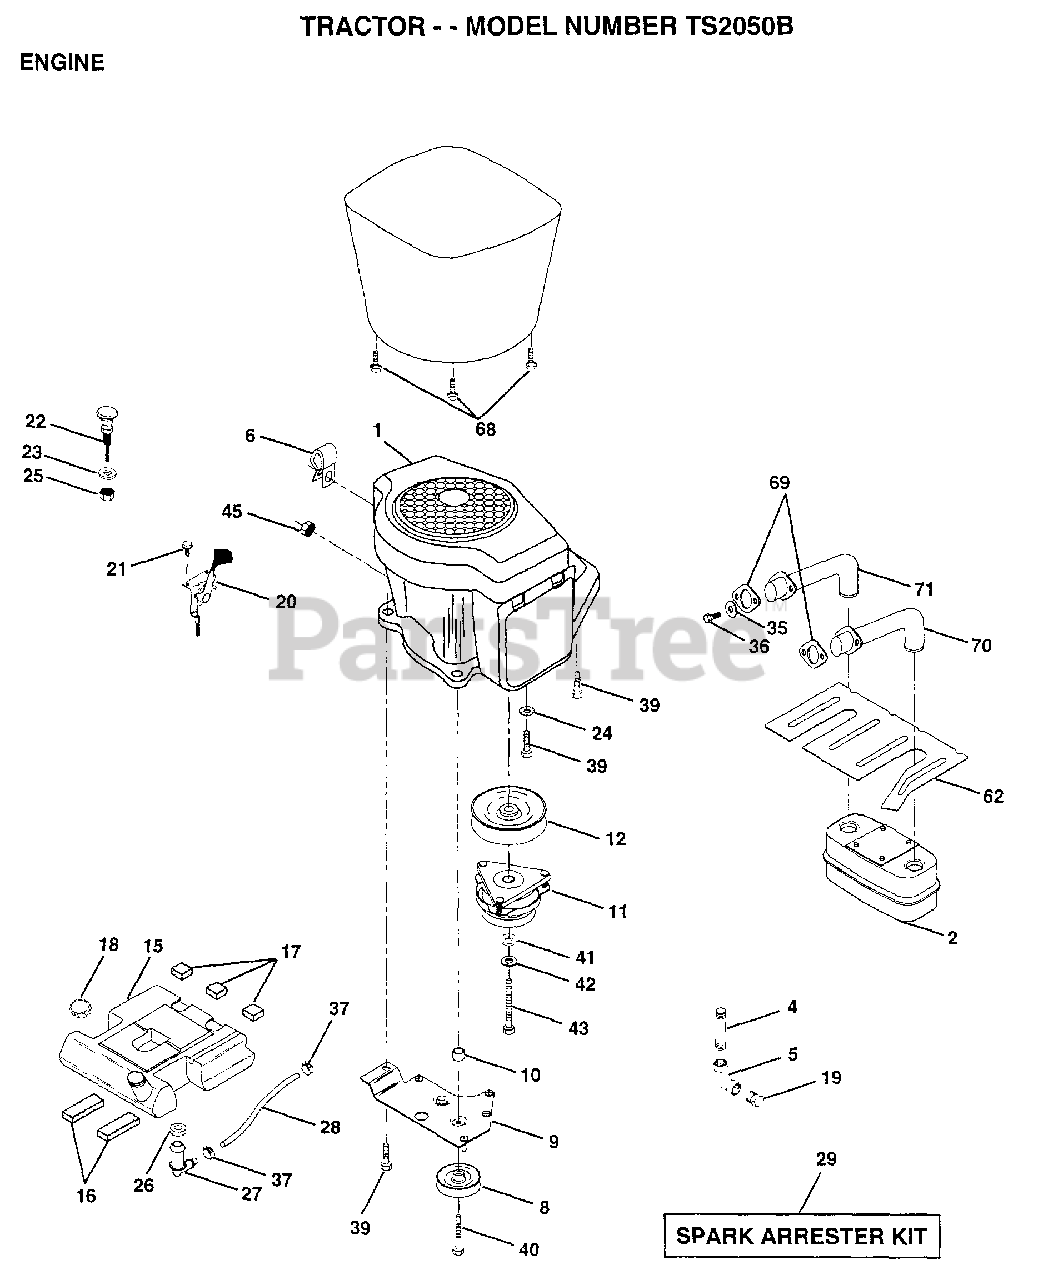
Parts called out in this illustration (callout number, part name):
1	ENGINE, ONAN
2	MUFFLER ASM-ONAN
5	ELBOW
6	CLAMP.TUBE.DBL.EN
10	BUSHING.
12	PULLEY.ENGINE.VGT
15	TANK FUEL REAR
16	PAD IDLER TI
17	PAD-SPACER LT
18	CAP ASM FUEL
19	PLUG T
21	SCREW LT
23	WASHER
24	LOCKWASHER
25	"NUT,KEPS 3/8-24IM"
26	BUSHING OUTLET T
27	STEM.TANK.FUEL
29	SPARK ARREST KIT
35	LOCKWASHER
36	SCREW
37	HOSE CLAMP
39	SCREW LT
40	SCREW.3/8-16X3.25
41	WASHER
42	LOCKWASHER
43	BOLT.7/16-20X4.25
45	NUT FLANGE M8-125
50	"DUCT-AIR,ONAN,YP"
62	"SHIELD-HEAT,ONAN"
64	SCREW
65	WASHER
68	"SCREW-TT,10-32 FL"
69	GASKET-MUFFLER )
70	"PIPE-EXHAUST,LH"
71	"PIPE-EXHAUST,RH"
